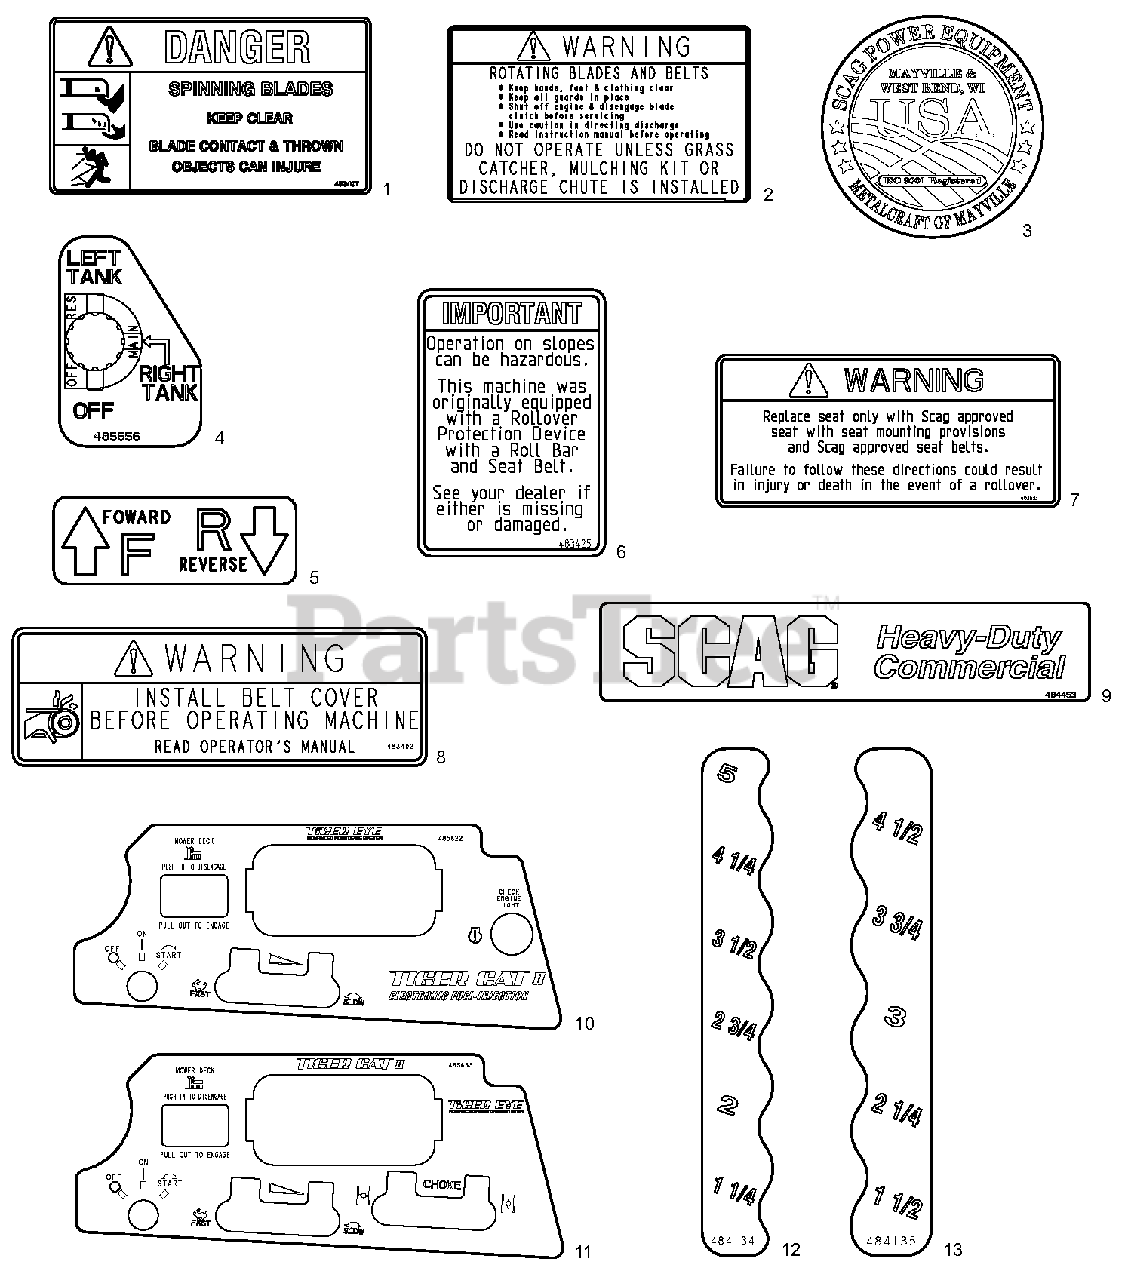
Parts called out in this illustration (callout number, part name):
1	Decal, Danger-Spinning Blades
2	Decal, Warning-Rotating Blades
3	Decal, Metalcraft - USA
4	Decal, Fuel Valve Position
5	Decal, Traction Control
6	Decal, ROPS
7	Decal, Seat Replacement
8	Decal, Belt Cover
9	Decal, Heavy Duty Commercial
10	Decal, Instrument Panel - EFI
11	Decal, Instrument Panel
12	Decal, Deck Height - LH
13	Decal, Deck Height - RH
